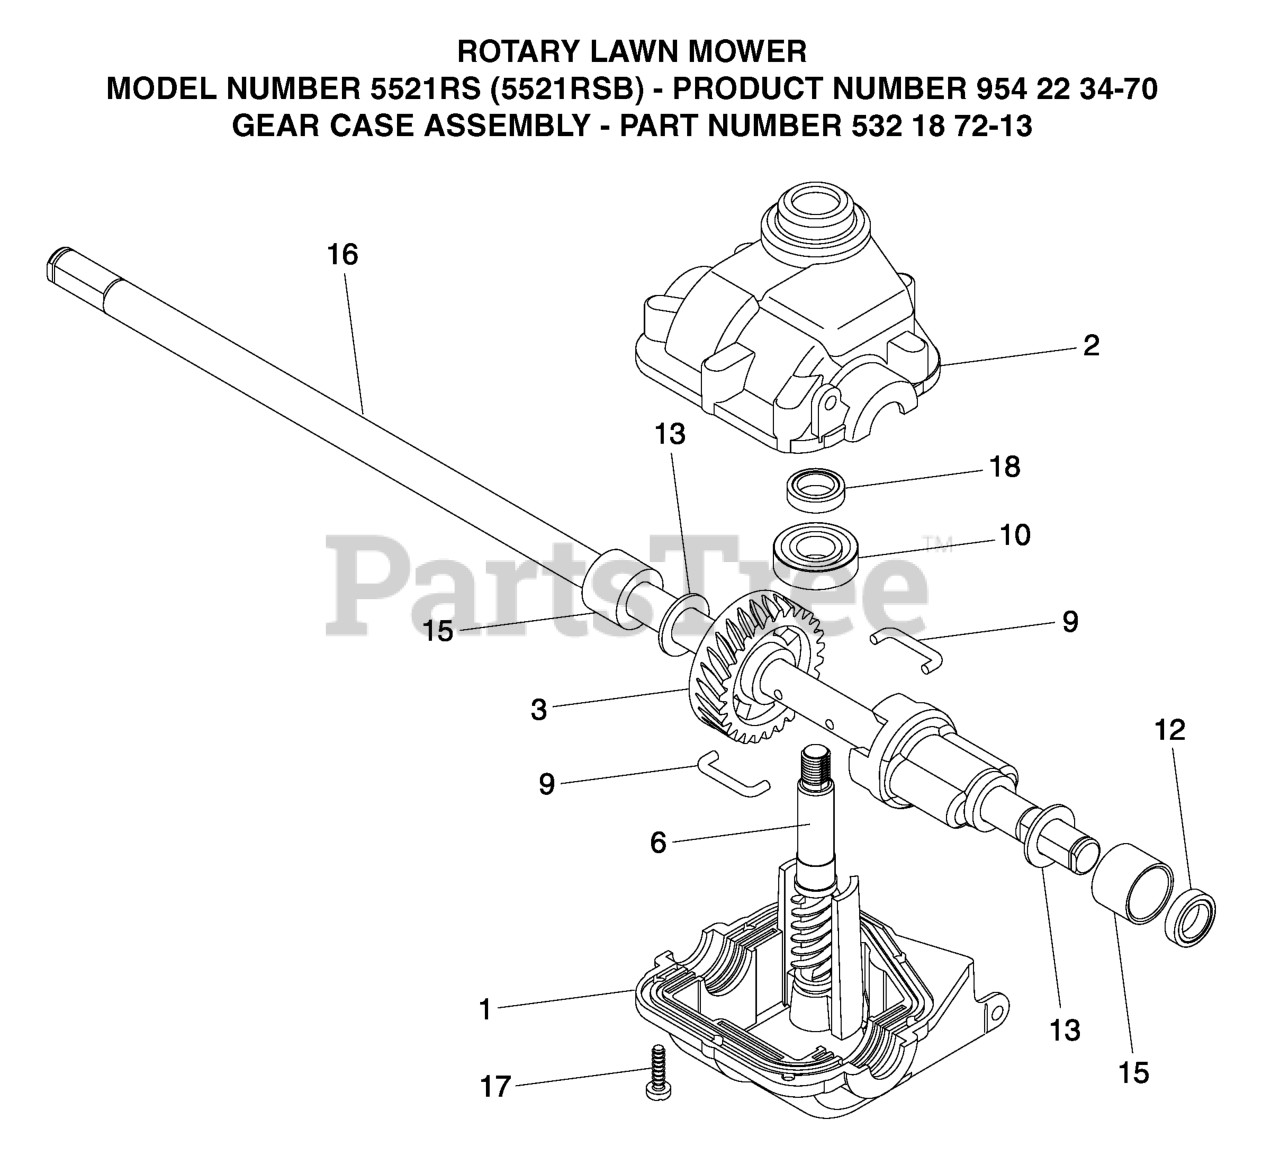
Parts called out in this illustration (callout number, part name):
1	CASE, LOWER
2	CASE, UPPER
3	GEAR.24.TOOTH.WALK.MOWER
6	SHAFT INPUT
9	WIRE, FORMED (15966)
12	SEAL.OUTPUT.SHAFT
16	SHAFT, OUTPUT
18	SEAL INPUT SHAFT
